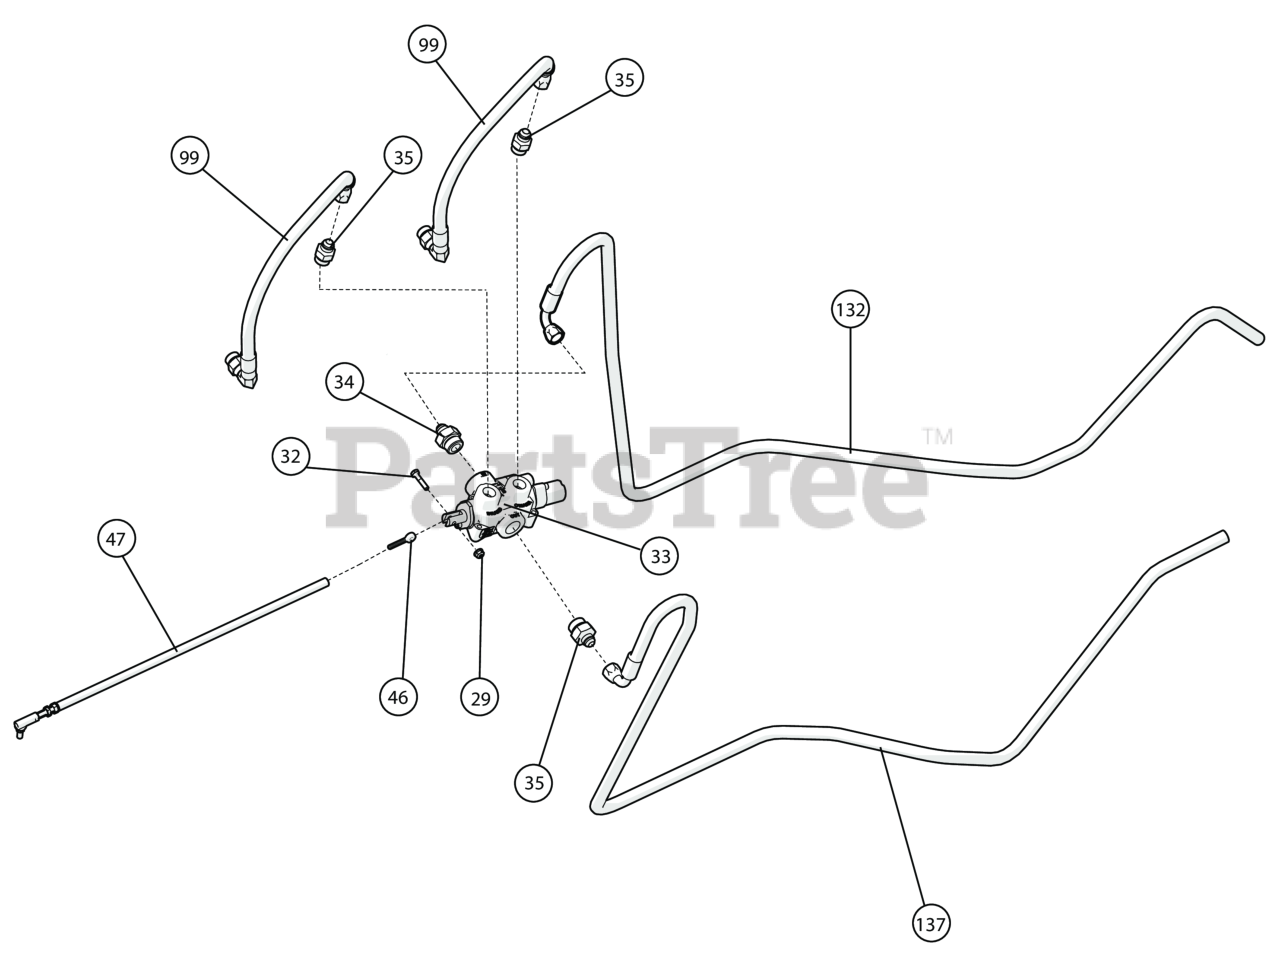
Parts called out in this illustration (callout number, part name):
29	NUT-HEX-NYLK, FLG .250"-20 ZP
32	SCREWCAP 1/4"-20X1 1/4" HCS ZP
33	VALVE, HYDRAULIC, .250 CROSSHOLE
34	ADAPTER, HYDRAULIC, SAE-12 TO 1/2 JIC
35	ADAPTER, HYDRAULIC, SAE-10 TO 1/2 JIC
46	ROD END, 1/4-28 X 3.50 LG
47	ROD, TIE, VALVE CONTROL
99	VALVE TO MOTOR HOSE 23" OAL
132	PUMP TO VALVE INLET HOSE 90" OAL
137	FILTER TO VALVE OUTLET HOSE 88" OAL
